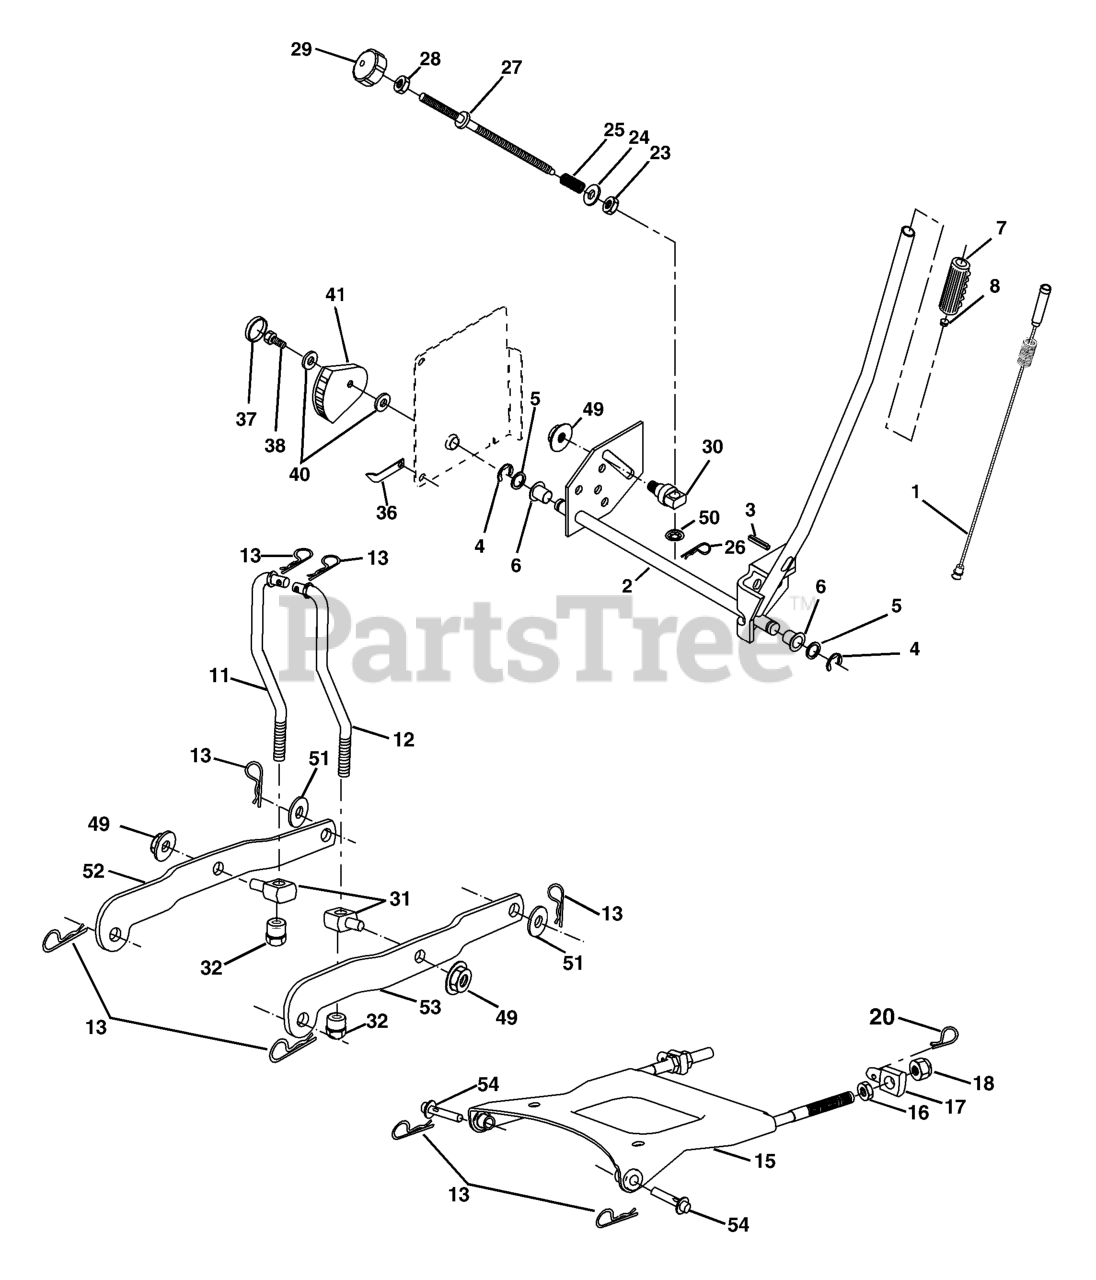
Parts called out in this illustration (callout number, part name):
1	WIRE ASM INNER W/ PLUNGER LT
2	SHAFT ASM R HANDLE
3	PIN GROOVE.
4	RETAINING RING LT
6	BEARING.NYLON
7	GRIP HANDLE
8	PLUNGER BUT KIT
11	LIFT LINK LH
12	LIFT LINK RH
13	RETAINER-SPRNG RB
15	PLATE ASM SUSP FRONT
16	NUT.HEX.JAM.1/2-13
18	NUT.LK.W/WSH.1/2.
20	SPRING RETAINER
25	SPRING**
26	RETAINER CLIP
27	ROD ADJ LIFT
28	NUT
29	KNOB INF 3/8-16
32	NUT, LIFT LINK 7/16-20
36	POINTER, HEIGHT INDICATOR(2 2)
38	SCREW 5/16-18X1
41	IND. HEIGHT STLT
49	NUT
50	NUT PUSH M
51	Washer 17/32 x 7/8 x 16 Ga.
52	ARM SUSP. REAR LH
53	ARM SUSP REAR RH
54	PIN.FLANGE
